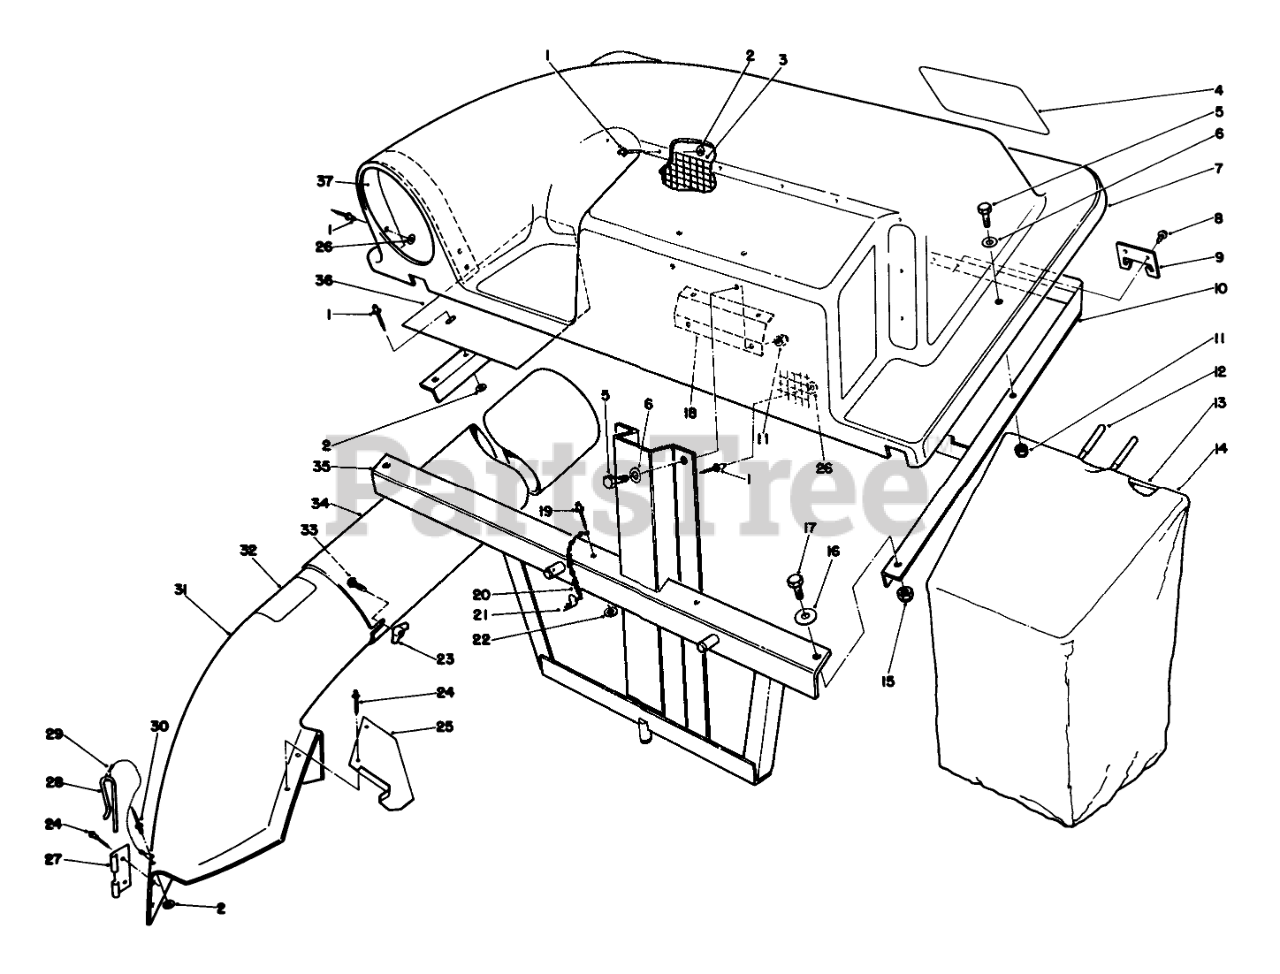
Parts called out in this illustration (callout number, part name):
1	RIVET-POP
2	WASHER-PLAIN
3	SCREEN
4	DECAL-BAGGER, TWIN
5	SCREW-HH
6	WASHER-PLAIN
7	COVER-BAGGER, TWIN
8	SCREW-HWH
9	BRACKET-FRAME, BAG
10	Cover-Frame
11	NUT-LOCK, NI
12	GRIP-HANDLE, BAG
13	Frame-Bag
15	NUT-LOCK, NI
16	WASHER-FLAT
17	SCREW-HH
18	Plate-Backup
20	10 LINK CHAIN W/O HOOK
21	PIN-HAIR
22	WASHER-BACK
23	NUT-WING SPECL
24	RIVET-BLIND
25	CHUTE SUPT BRKT
26	WASHER-FLAT
27	BRACKET-MOUNTING, CHUTE
28	PIN-LOCKING, CHUTE
29	LANYARD
30	RIVET-BLIND
31	Chute Assembly (Incl. Ref. #24-30 & 32)
32	DECAL-DANGER
33	BOLT-CARR
34	TUBE(ROUND&LONG)
35	Frame-Mounting
36	Baffle
37	Support Inlet
